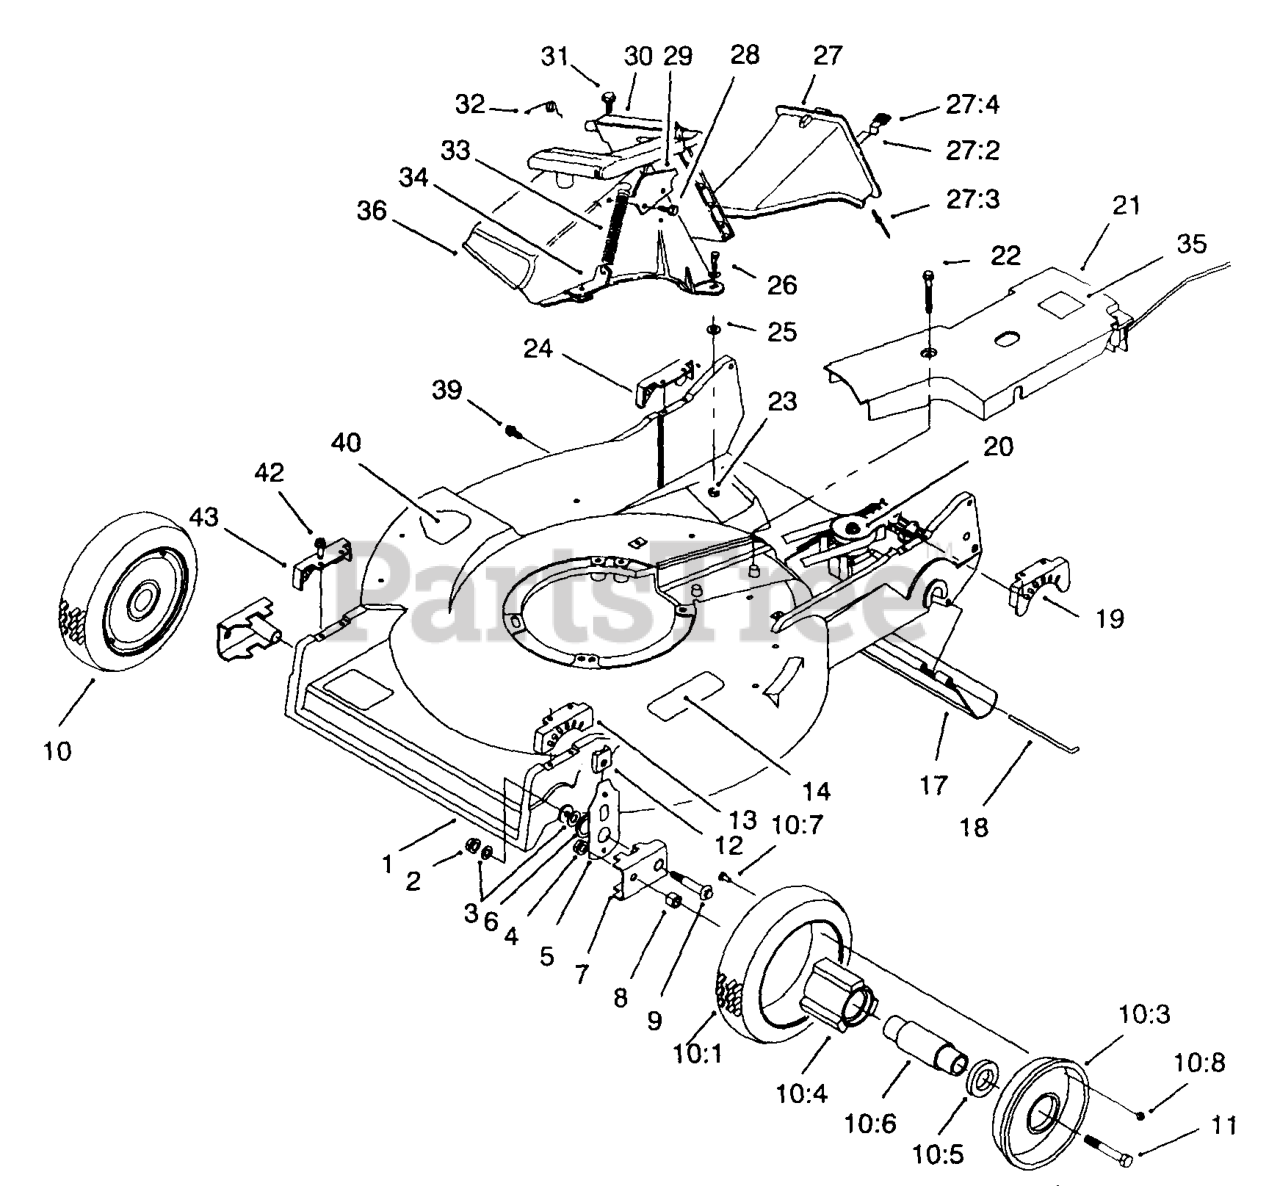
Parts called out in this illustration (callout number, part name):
35	Label - Grease
102	Asm - Wheel
273	Rivet
